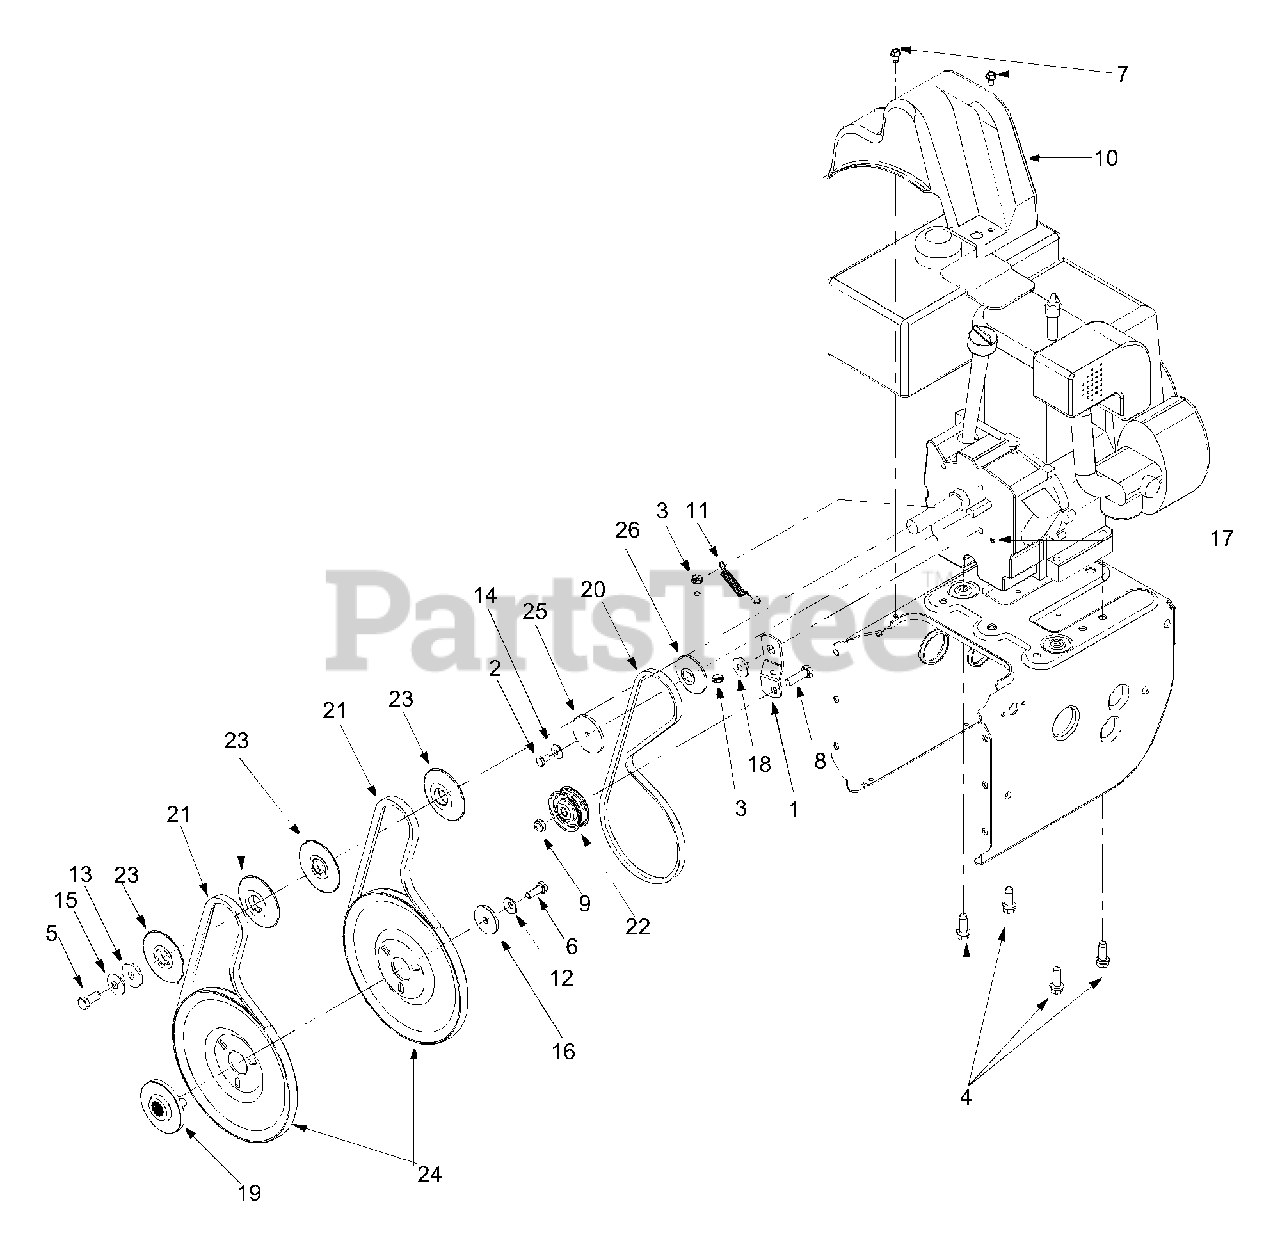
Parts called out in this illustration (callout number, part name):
3	Hex Screw w/ patch: 5/16-24 x 0.75"
4	Hex Washer Head TT Sems Screw
5	Hex Bolt 3/8-24 x .875" Gr.8
6	Hex Screw w/ Patch: 5/16-24 x .875"
7	Hex Washer Head TT
8	Hex Screw: 3/8-16 x 1.0"
9	Top Lock Jam Nut: 3/8-16
10	Belt Cover
11	Extension Spring
12	Bellevile Washer
13	Flat Washer
14	Bell Washer
15	Bell Washer
16	Flat Washer
17	Grease
18	Shoulder Spacer
19	Adapter Pulley
20	V-Belt
21	Belt
22	Flat Idler
23	Pulley Half
24	Auger Pulley
25	Pulley Half
26	Pulley Half
